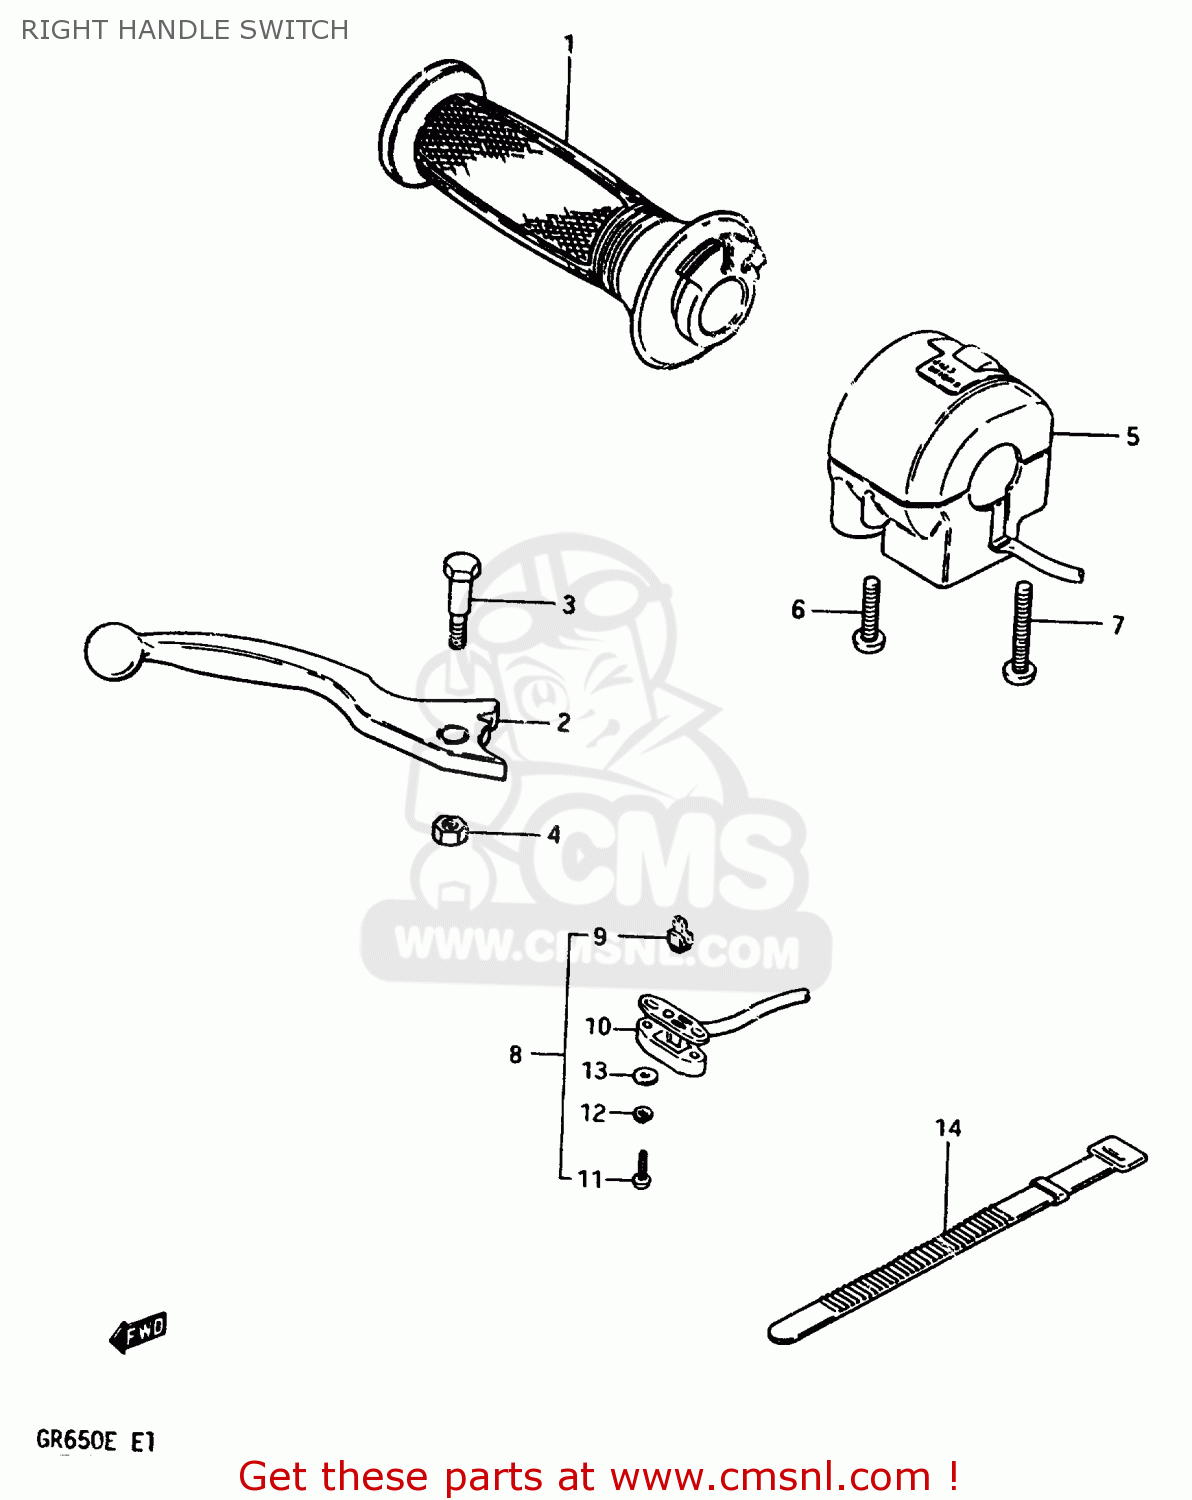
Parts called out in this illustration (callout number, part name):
1	GRIP,THROTTLE
2	LEVER,BRAKE
3	BOLT
4	NUT 6MM
5	SWITCH ASSEMBLY,HANDLE,RIGHT
6	SCREW
7	SCREW
8	SWITCH ASSEMBLY
9	CONTACT,SWITCH
10	COVER,FR BK TERMINAL BASE
11	SCREW
12	LOCK WASHER
13	WASHER
14	CLAMP(L:120)
